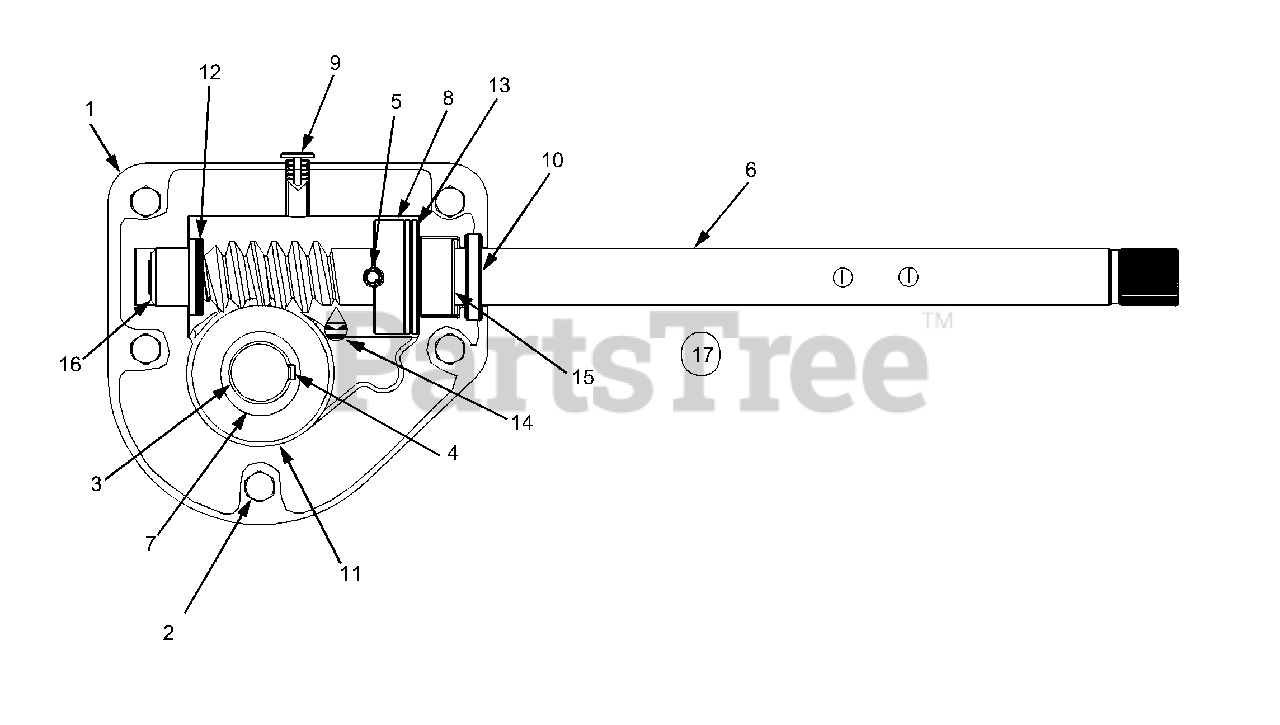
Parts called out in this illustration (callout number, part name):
1	Housing R.H.
2	Hex Screw 1/4-20 x .75
3	Spiral Axle 22"
4	Key
5	Pin-Spiral
6	Shaft-Worm
7	Gear-Worm
8	Collar-Thrust
10	Seal-Oil
11	Washer-Flat
12	Washer-Flat
13	Washer-Flat
14	Grease
15	Bearing-Flange
16	Bearing-Flange
17	Ass'y. Complete 22"
